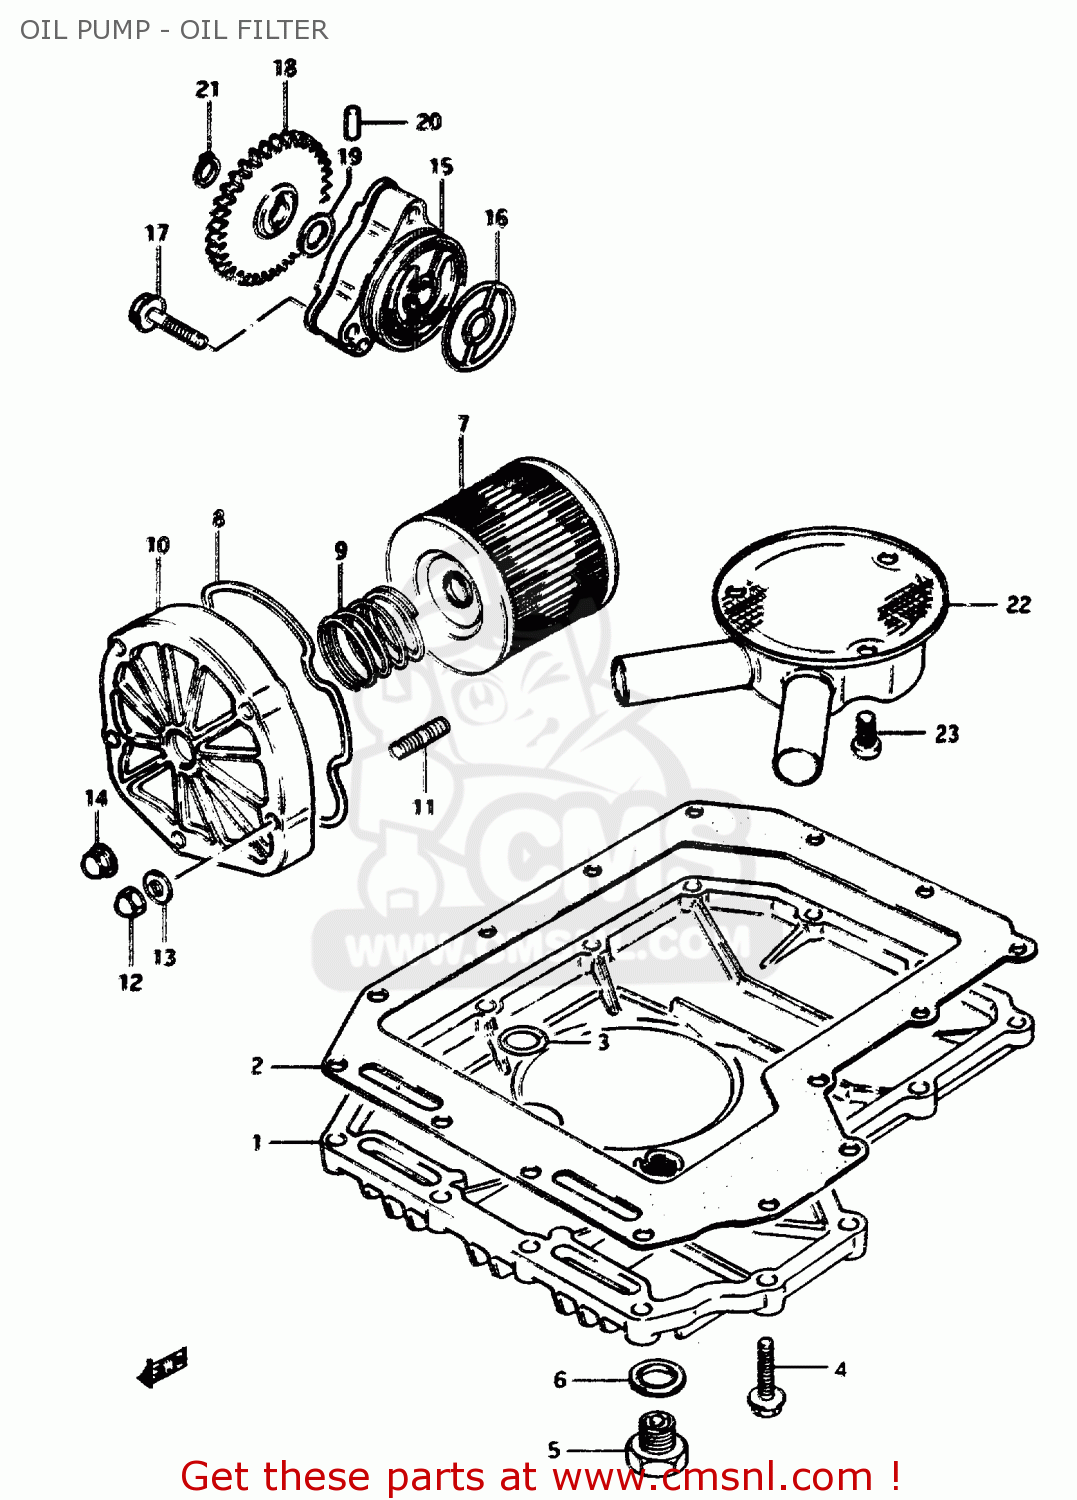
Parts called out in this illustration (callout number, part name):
1	PAN,OIL
2	GASKET,OIL PAN (MCA)
3	O RING(D:3.2,ID:12.9)
4	BOLT
5	PLUG
6	GASKET(14X19.2X2) (NAS)
7	FILTER ASSY,ENGINE OIL
8	O RING,OIL FILTER CHAMBER CAP
9	SPRING
10	CAP,ENGINE OIL FILTER
11	STUD 6X25
12	NUT 6MM
13	WASHER
14	NUT
15	PUMP ASSY,ENGINE OIL
16	O RING,OIL PUMP
17	BOLT(6X32)
18	GEAR,ENG OIL PUMP DRIVEN(NT:33
19	SHIM
20	PIN(4X15.8)
21	CIRCLIP
22	STRAINER,ENGINE OIL
23	SCREW 6X12
